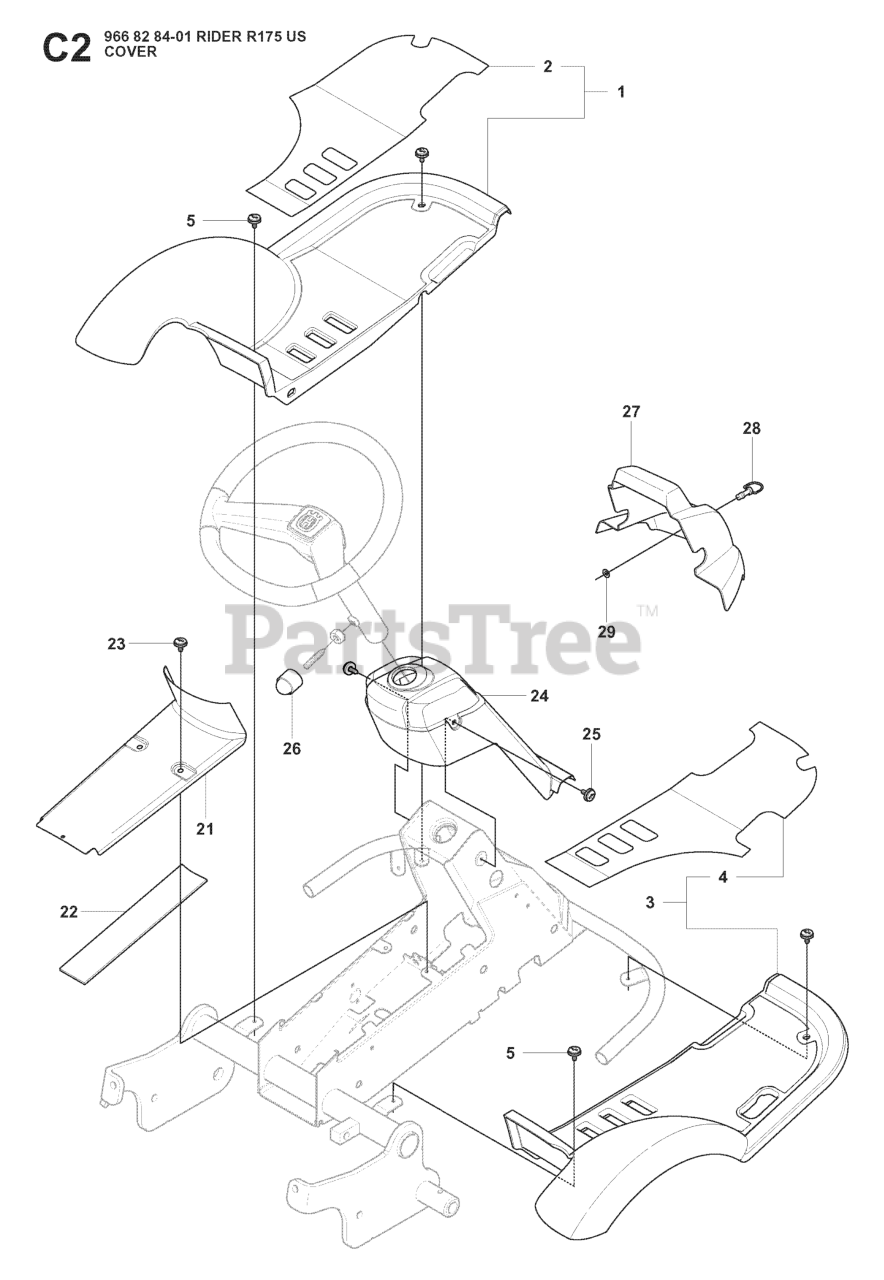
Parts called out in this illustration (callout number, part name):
1	FOOT PLATE
3	FOOT PLATE
26	PROTECTIVE COVER
28	BOLT
